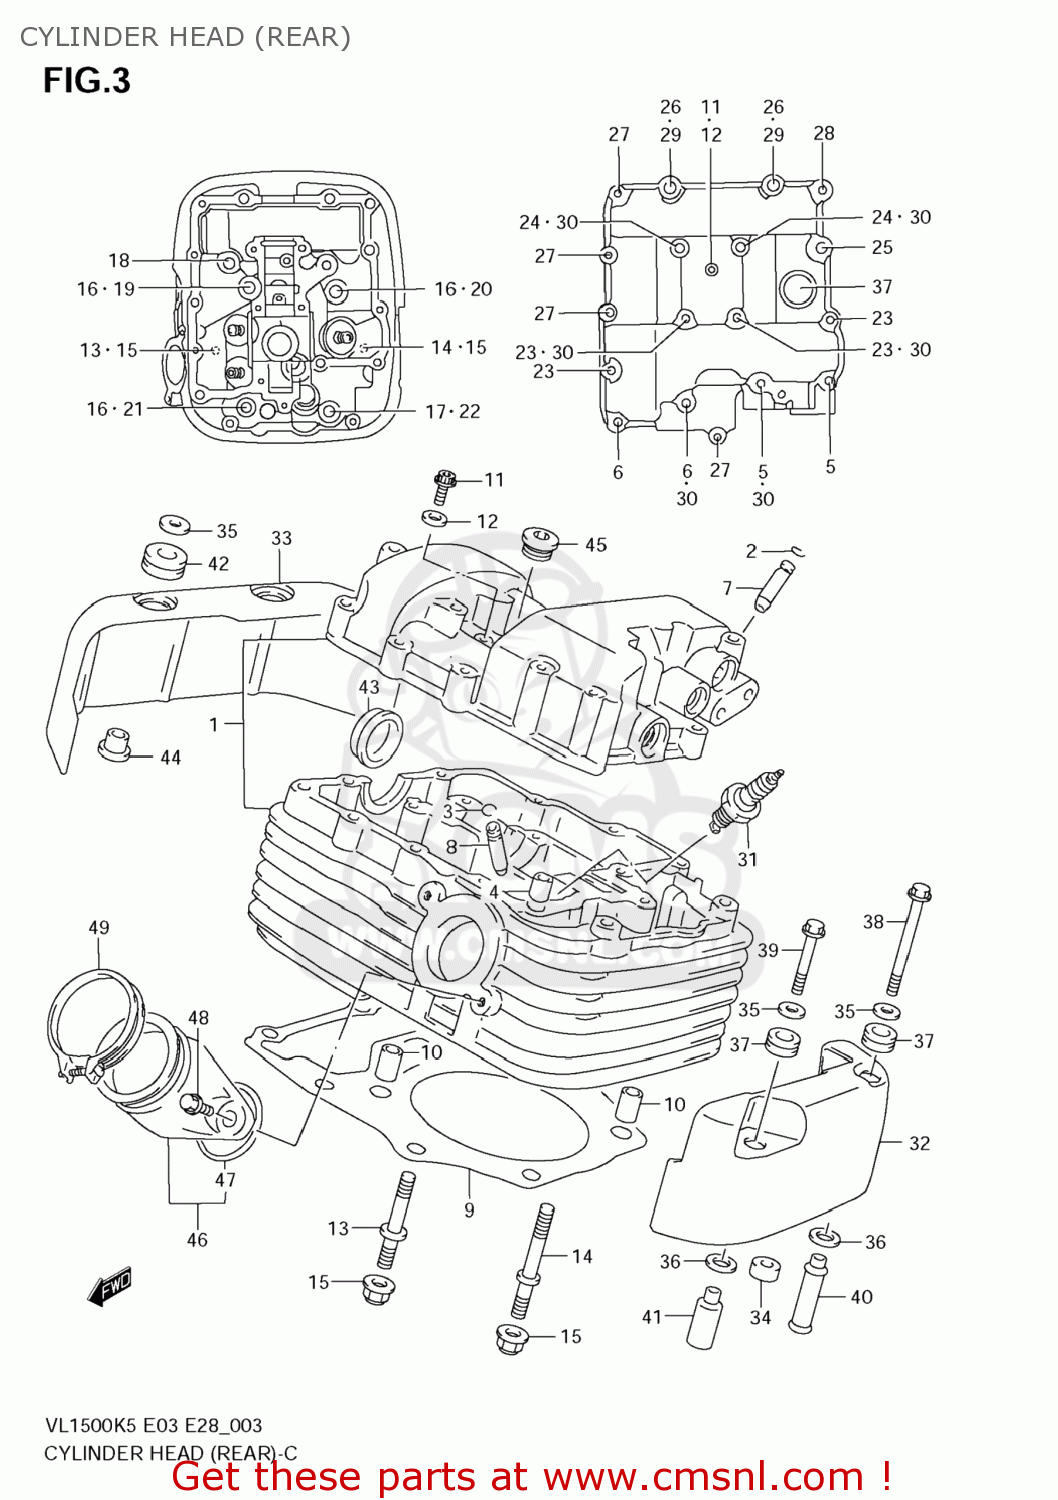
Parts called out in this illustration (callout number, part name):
1	HEAD ASSY,CYLINDER RR
2	RING,SNAP
3	RING,SNAP
4	PIN(6.2X8X11)
5	BOLT(6X60)
6	BOLT(6X55)
7	GUIDE,INTAKE VALVE
8	GUIDE,INTAKE VALVE
9	GASKET,CYLINDER HEAD RR (NAS)
10	PIN
11	BOLT
12	GASKET(6.2X13X1.2) (NAS)
13	BOLT,STUD
14	BOLT,STUD
15	NUT
16	WASHER(10.5X22X2.3)
17	GASKET(10.5X22X2) (NAS)
18	BOLT(8X57)
19	BOLT(10X180)
20	BOLT(10X190)
21	BOLT(10X200)
22	BOLT(10X215)
23	BOLT(6X50)
24	BOLT(6X45)
25	BOLT(8X130)
26	BOLT(8X268)
27	BOLT
28	BOLT
29	WASHER(8.5X24X1.6)
30	GASKET(5.8X13X1.2) (NAS)
31	SPARK PLUG X22E
32	CAP,CYLINDER HEAD COVER RR,L
33	CAP,CYLINDER HEAD COVER RR,R
34	CUSHION,R CAP
35	WASHER(6.5X18X1.6)
36	WASHER(9.5X20X1)
37	CUSHION
38	BOLT
39	BOLT
40	SPACER,CYL HEAD COVER CAP NO.1
41	SPACER,CYL HEAD COVER CAP NO.2
42	CUSHION
43	PLUG(OD:30)
44	BUSH
45	PLUG,22X11
46	PIPE ASSY,INTAKE RR
47	O RING(D:1.9,ID:40.7)
48	BOLT(6X16)
49	CLAMP
